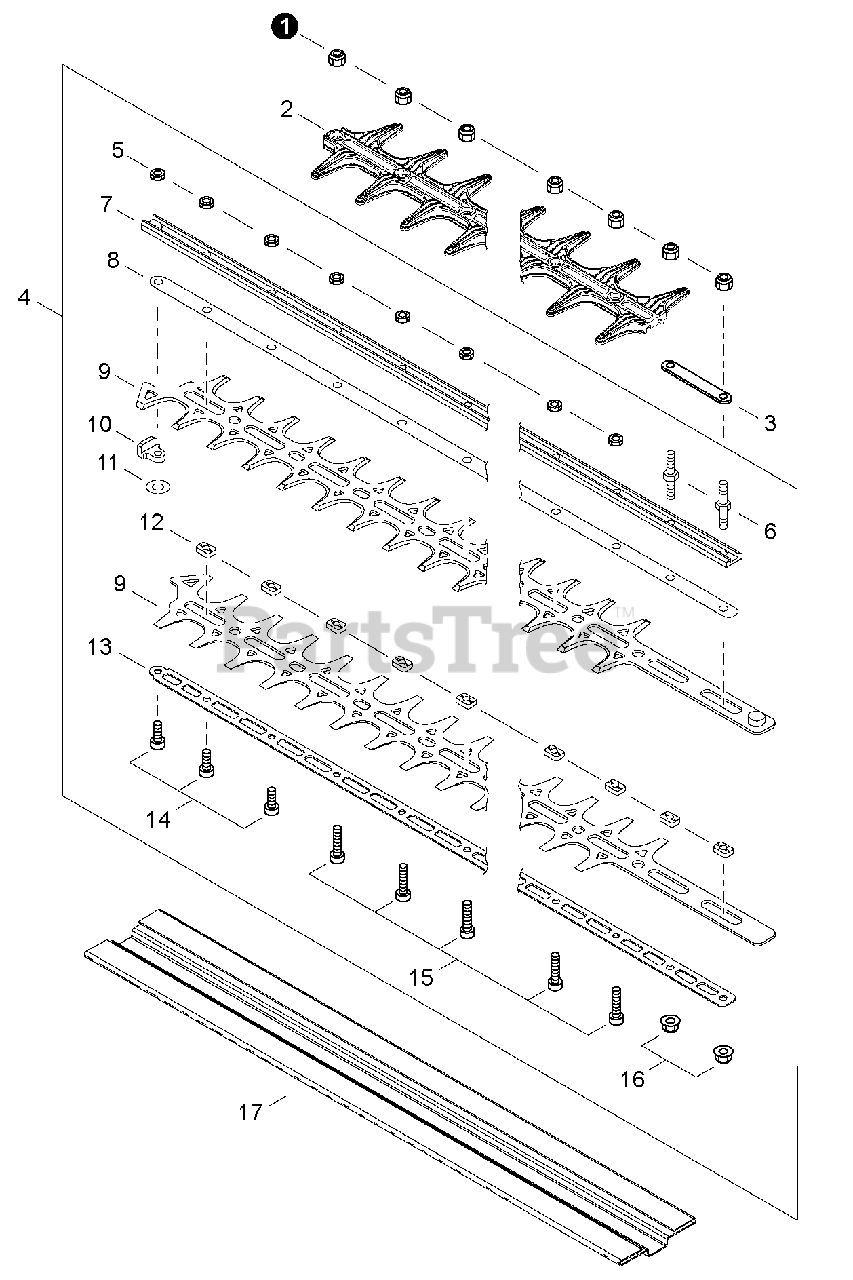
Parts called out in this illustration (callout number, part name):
2	GUARD, CUTTER BLADE
3	PLATE, EYE
4	CUTTER ASSY, 30"
6	STUD, MOUNTING M5
7	SUPPORT, BLADE 30"
8	SUPPORT, BLADE 30"
9	CUTTER 30"
13	SUPPORT, BLADE 30"
14	BOLT, TORX 5×16
15	BOLT, TORX 5×25
17	SCABBARD
